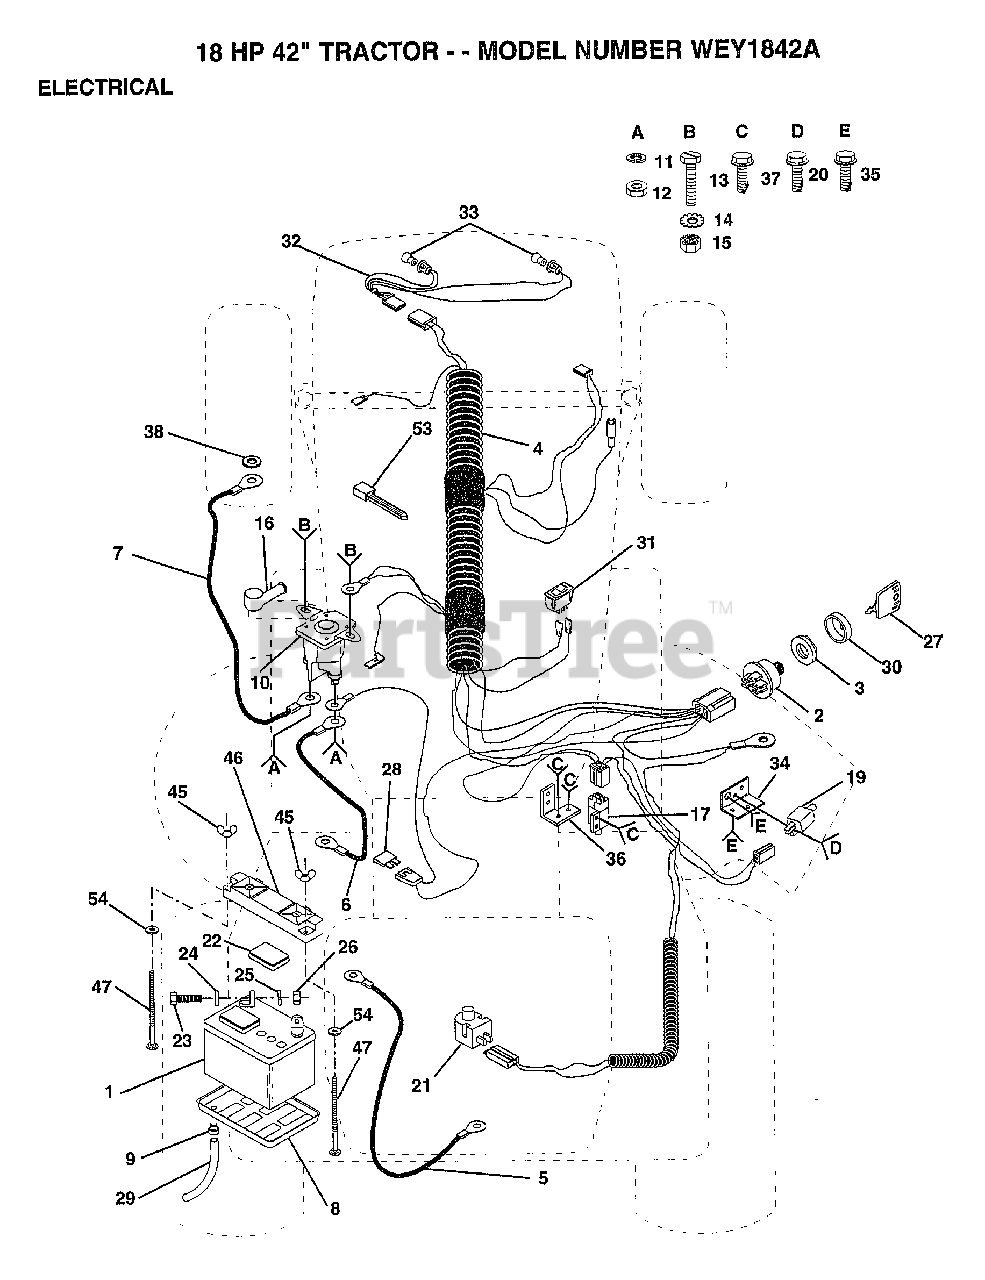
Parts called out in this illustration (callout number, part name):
3	NUT IGNITION
4	HARNESS.IGN.B&S
5	CABLE T
6	CABLE-BATTERY T
7	"CABLE T, BATTERY"
8	"TRAY T, BATTERY"
9	HOSE CLAMP T
12	NUT
13	BOLT
15	NUT
17	SWITCH INTERLOCKT
19	SWITCH-INTER. GT
20	SCREW
21	SWITCH SEAT
22	"CAP,BATTERY "
23	BOLT LT
24	WASHER
25	LOCKWASHER
27	KEY
28	FUSE HYT
29	"DRAIN TU T, BATT"
31	SWITCH LT
34	BRACKET LT
35	SCREW
36	SWITCH BRACKET
37	SCREW
47	BOLT
53	WIRE TIE
54	WASHER.3/4X1X18GA
